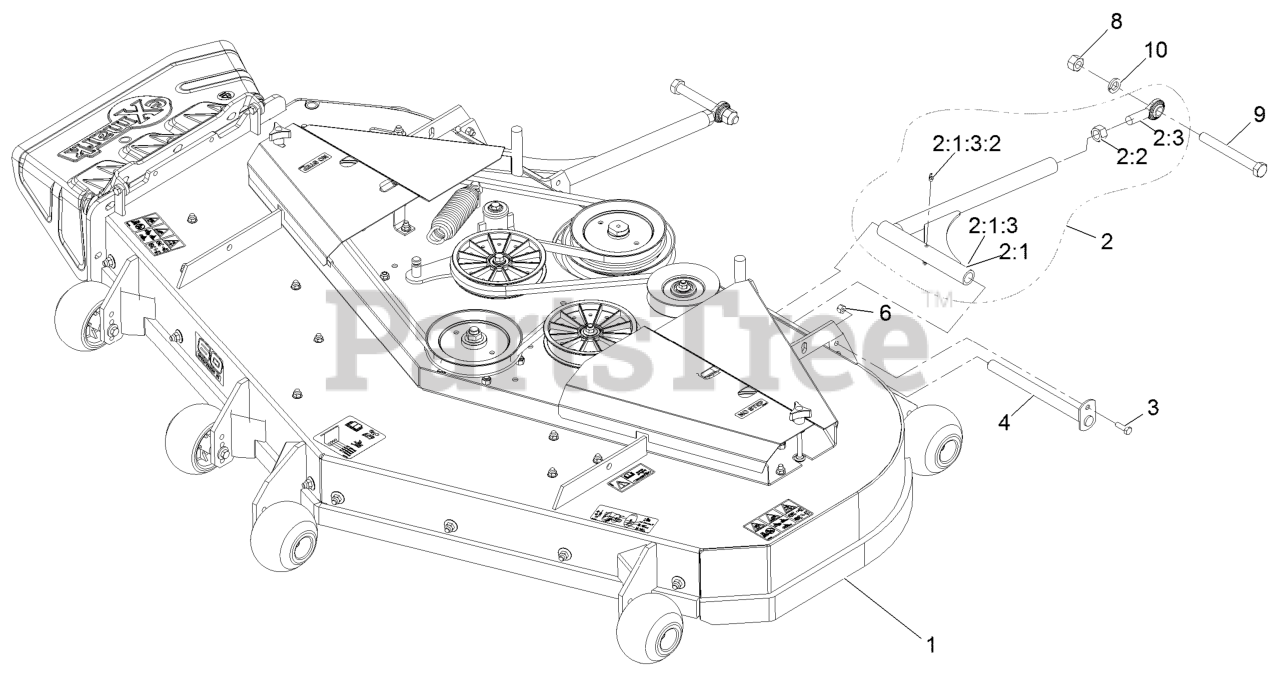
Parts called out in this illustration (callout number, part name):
1	ASM-Deck Complete 605
2	ASM,DECK STRUT XS 60
2:1	STRUT-DECK
2:1:3	Tube And Zerk ASM
2:2	NUT-HEX
2:3	BALLJOINT-SPHERICAL
3	SCREW-HH
4	PIN-STRUT
6	NUT-LOCK, NI
8	NUT-HEX
9	SCREW-HH
10	WASHER-LOCK
